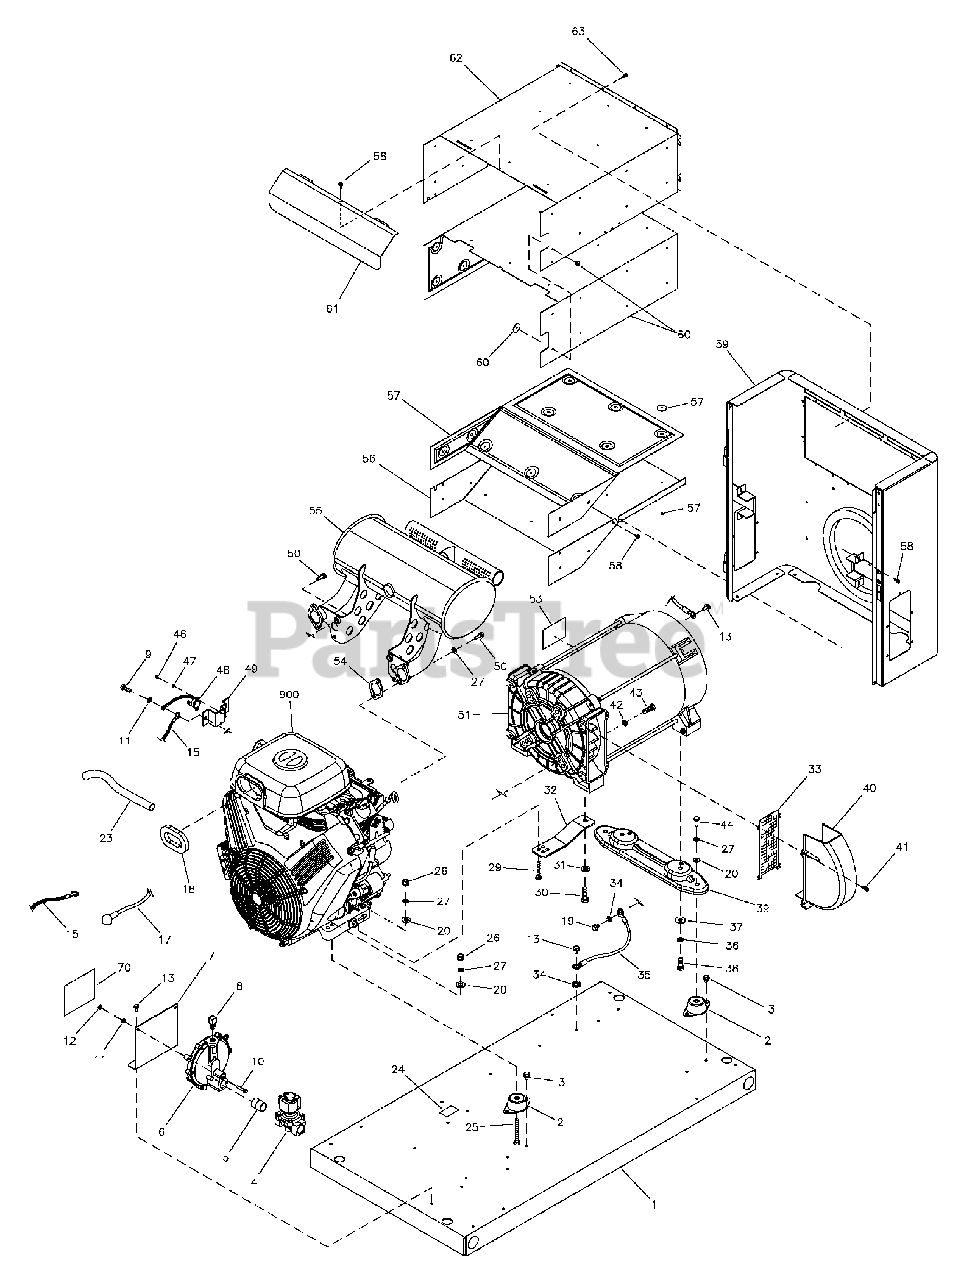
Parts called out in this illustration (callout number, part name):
2	MOUNT, Vibration
4	SOLENOID, Gas Fuel
6	REGULATOR, NG/LPG
7	BRACKET
9	* CAPSCREW, Hex Head, M6-1 x 16
10	* CAPSCREW, Hex Head, M6-1 x 30
11	* WASHER, Lock, 1/4
12	* NUT, M6-1
13	BOLT
15	CABLE, Battery, Black
17	CABLE, Battery, Red
18	TUBE
20	* WASHER, Flat, 5/16-M8
23	HOSE, Oil Drain
24	DECAL
25	* CAPSCREW, Hex Head, 5/16-18 x 2-1/2
26	* NUT, 5/16-18
27	* WASHER, Lock, 5/16-M8
29	* CAPSCREW, Hex Head, 5/16-18 x 2
30	* CAPSCREW, Hex Head, M12 - 1-3/4 x 35
31	* WASHER, M12
32	SUPPORT, Engine
34	* WASHER, Shakeproof, M6
36	* WASHER, Lock, 3/8
37	* WASHER, Flat, 3/8-M10
38	* CAPSCREW, Hex Head, 3/8-16 x 1
41	* SCREW, Taptite, M5.8 x 10
42	* WASHER, Lock, 3/8
43	* CAPSCREW, Socket Head, 3/8-16 x 1-1/4
44	* CAPSCREW, Hex Head, 5/16-18 x 3/4
46	* SCREW, Phillips Head, 4-40 x 3/16
47	* WASHER, Lock, #4
49	PLATE, Temp Switch
50	SCREW
51	ALTERNATOR, Complete
53	DECAL
59	BULKHEAD, Alternator
62	BOX, Muffler Top
900	** ENGINE
